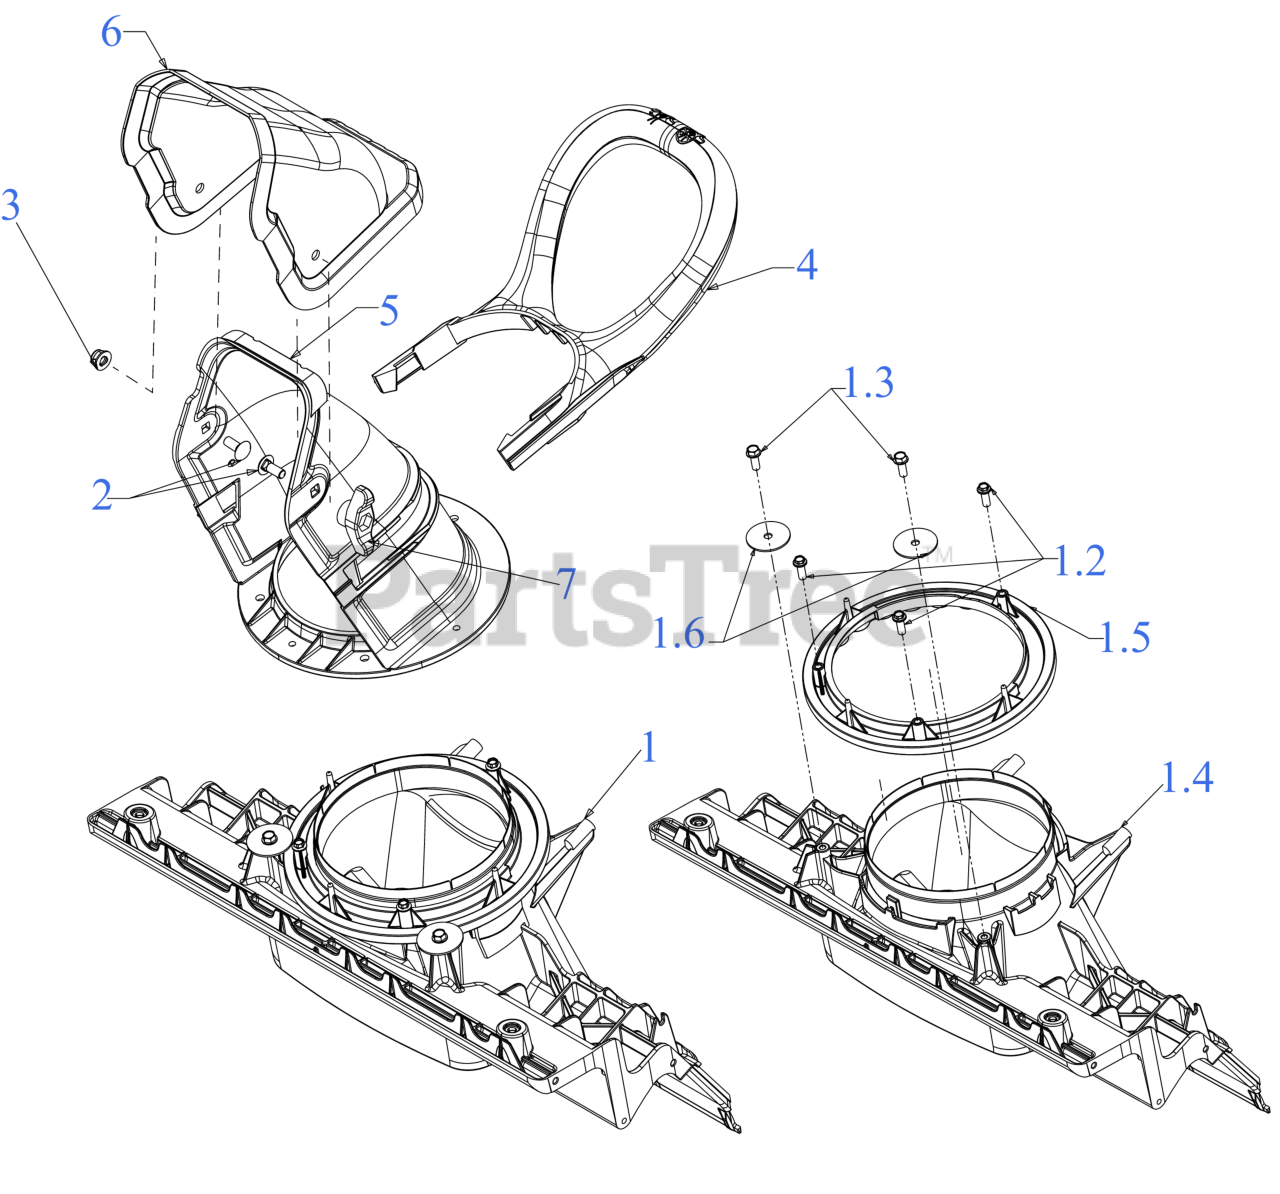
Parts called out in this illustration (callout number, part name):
1	CHUTE ADAPTER ASSEMBLY
1.2	SCREW 1/4 x .750
1.3	SCREW 1/4-15 x .750
1.4	CHUTE ADAPTER
1.5	CHUTE RING
1.6	FLAT WASHER
2	CARRIAGE BOLT 5/16-18 x .75
3	FLANGE LOCK NUT 5/16-18
4	CHUTE HANDLE
5	LOWER CHUTE 6.5"
6	UPPER CHUTE DEFLECTOR
7	WING KNOB 5/16-18
